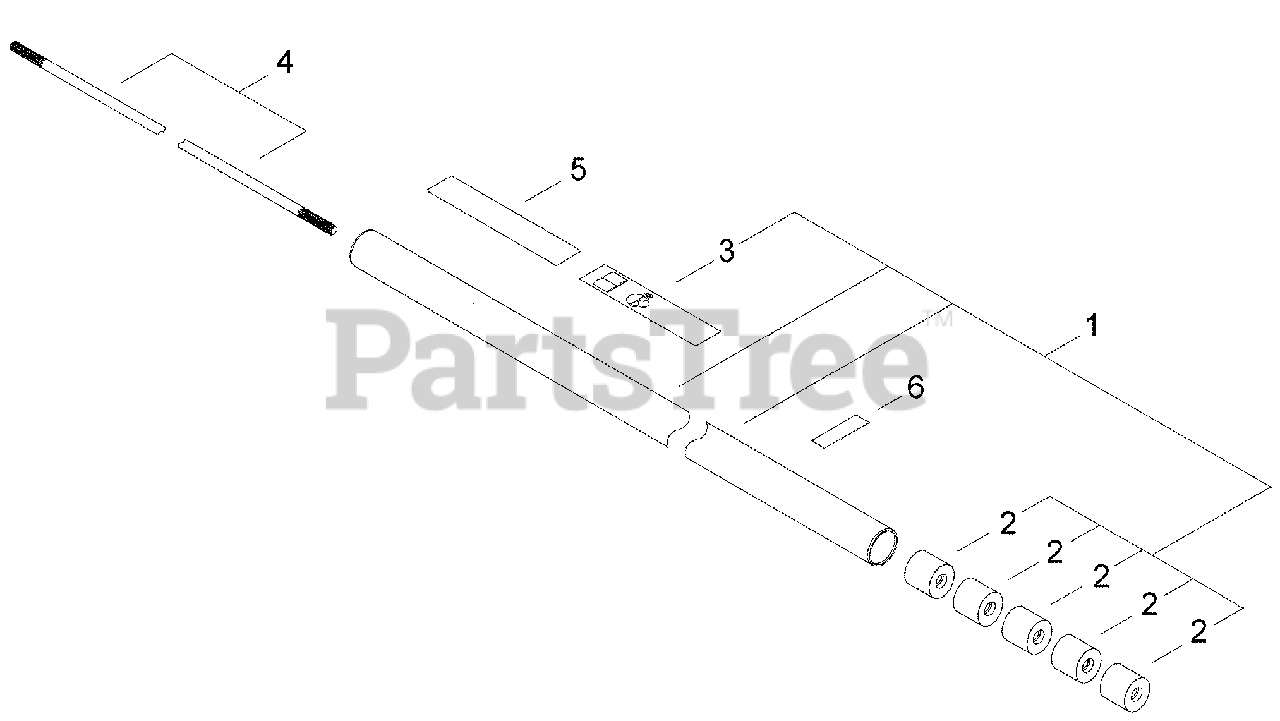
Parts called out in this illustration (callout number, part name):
2	BUSHING
3	LABEL, CAUTION (NON-BLADE CAPABLE)
4	MAINSHAFT
5	LABEL, SWISHER E4
6	LABEL, HANDLE
